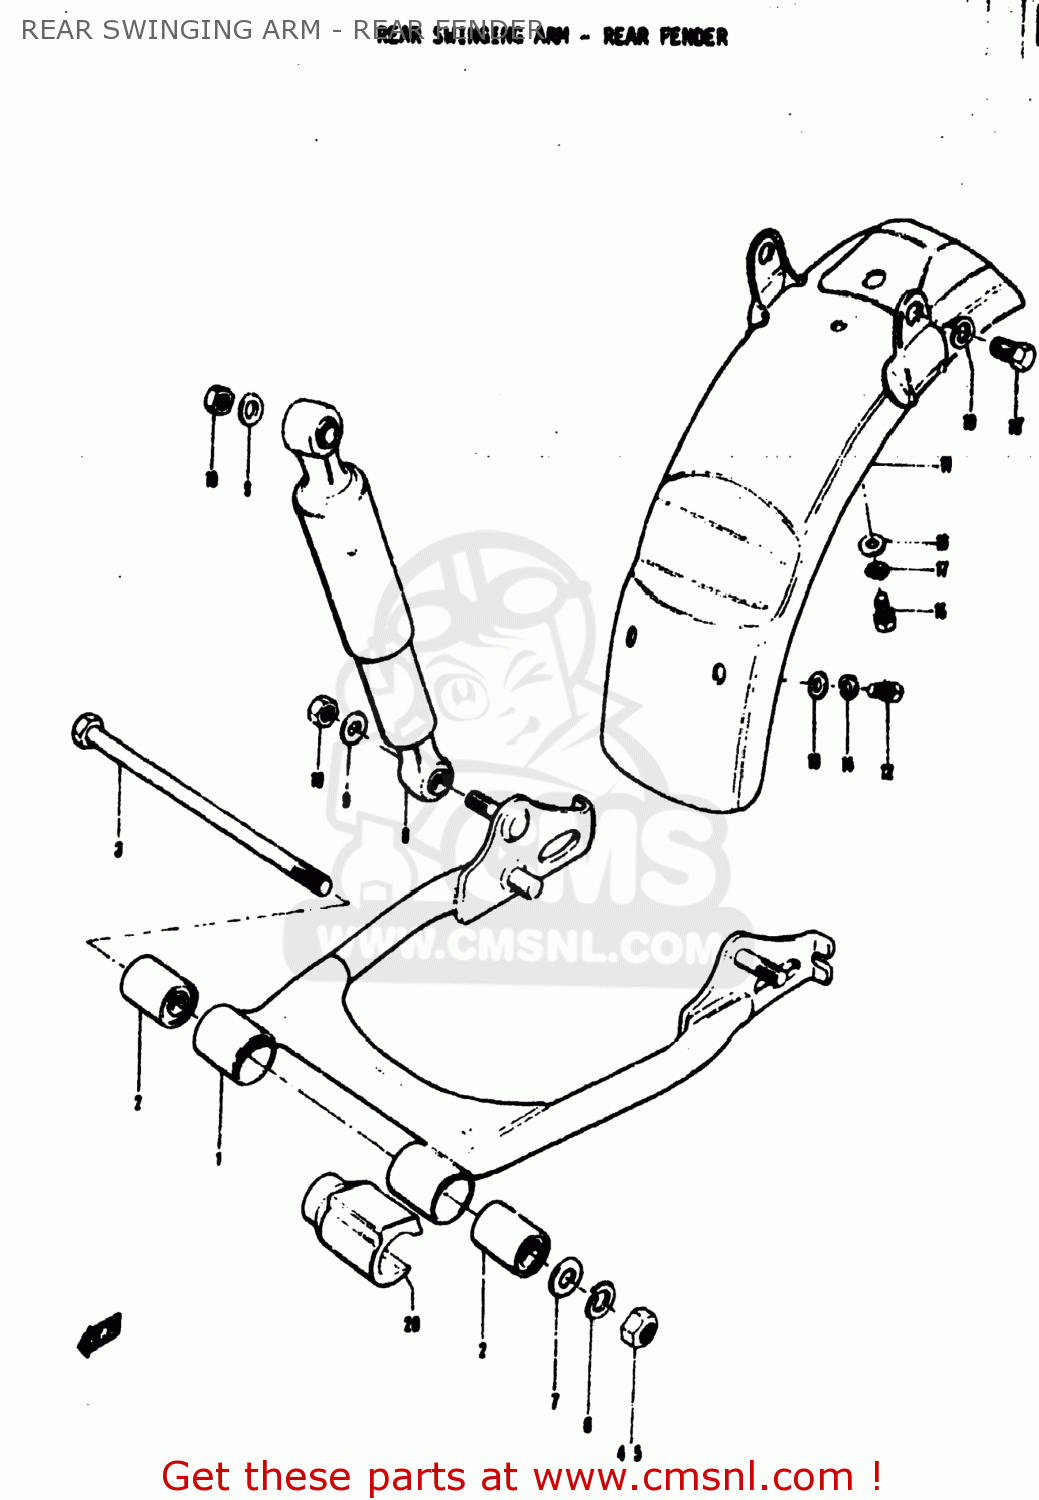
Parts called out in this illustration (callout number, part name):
2	BUSHING(10X23X35)
3	SHAFT,RR SHOCK ABSORBER UPR
4	NUT
5	NUT
6	LOCK WASHER
7	WASHER
9	WASHER
10	NUT
12	BOLT
13	WASHER 6MM
14	LOCK WASHER
15	BOLT
16	WASHER 6MM
17	LOCK WASHER
18	BOLT
19	LOCK WASHER
20	BUFFER,CHAIN TOUCH DEFENCE
